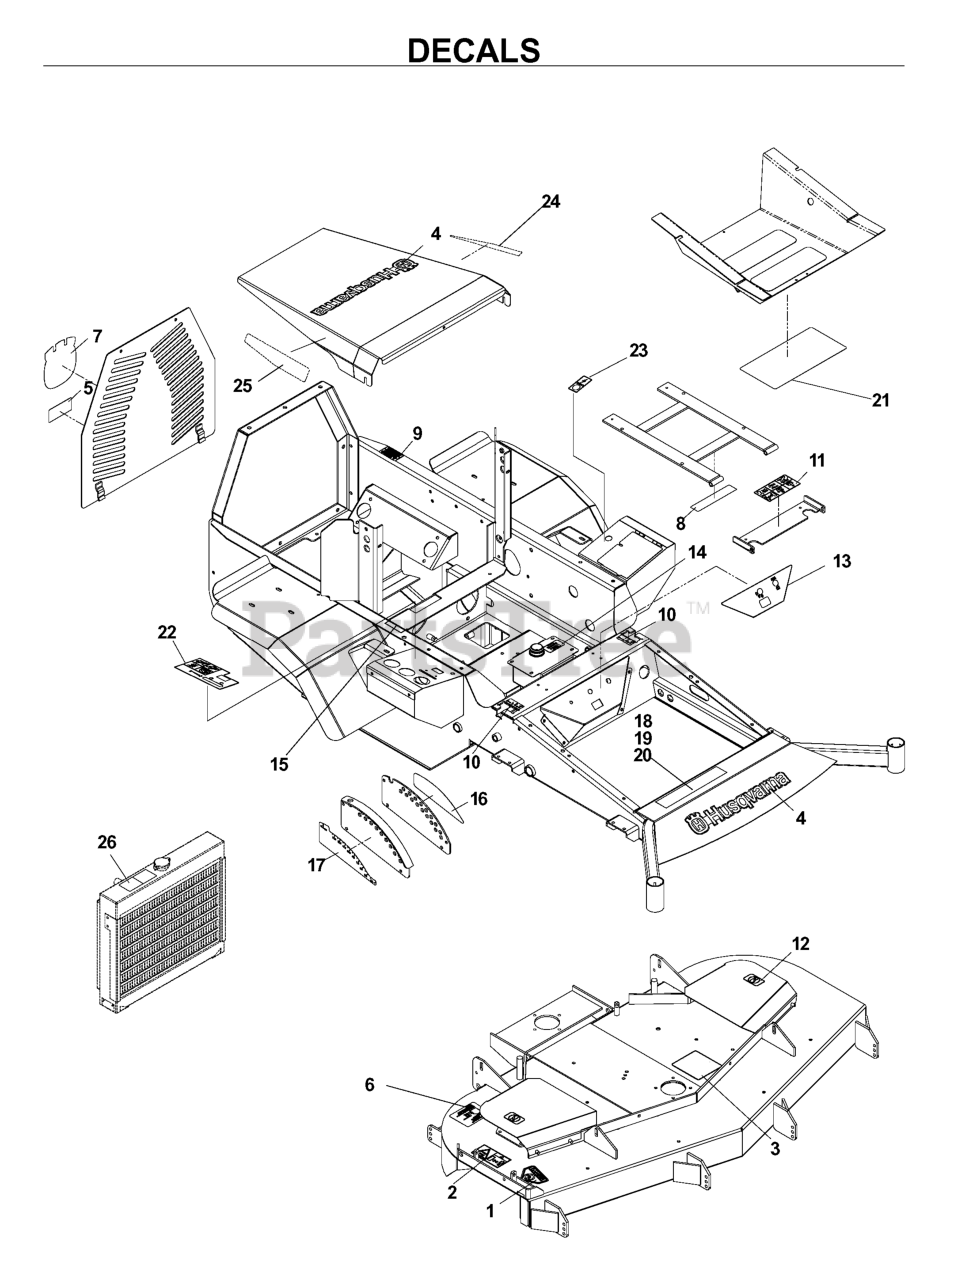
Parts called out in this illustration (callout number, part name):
1	DECAL, CPSC
2	DECAL, EURO SEVERING
3	DECAL, BELT ROUTING
4	DECAL, HUSQVARNA 17.5"
5	DECAL, BELT DRIVE
6	DECAL, ANTI SCALP
7	DECAL, LGE CROWN 7X6"
8	EURO DECAL-BATTERY WARNIN6
9	DECAL, PROP. 65
10	DECAL, MOTION CONTROL
11	DECAL, EURO WARNING
12	DECAL, NO STEP
13	DECAL, FRONT CONSOLE
14	DECAL, MOBIL 1
15	FUEL VALVE DECAL
16	DECAL, HEIGHT
17	DECAL, HEIGHT
18	DECAL - BZ6134D
19	DECAL - BZ7234D
20	DECAL - BZ6127D
21	DECAL, SERVICE
22	DECAL, RT CONSOLE
23	DECAL, 12V
24	DECAL, 34 TURBO LH
25	DECAL, 34 TURBO RH
26	DECAL, HOT
539100128	DECAL, EXHAUST
539108264	DECAL, 27HP DIESEL LEFT
539108265	DECAL, 27HP DIESEL - RIGHT
